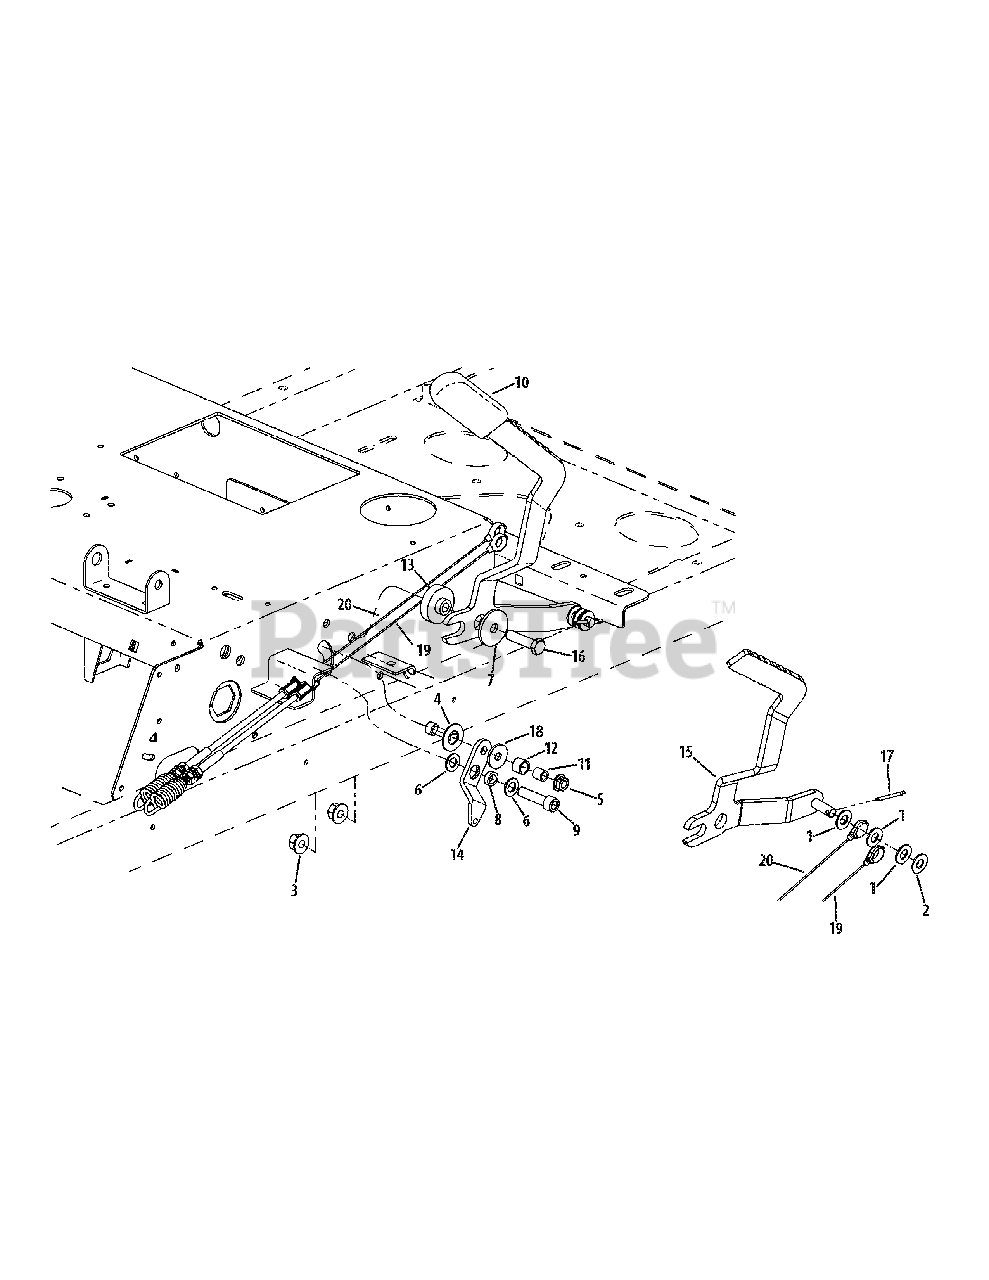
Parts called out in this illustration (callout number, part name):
1	Flat Washer, .406 x .812 x .062
2	Flat Washer, 3/8
3	Hex Nut, 3/8-16 Flange Lock
4	Slide Washer
5	Flange Lock Nut, 5/16-18
6	Washer, .375 x .738 x .063
7	Flat Washer, .390 x 1/5 x .134
8	Spacer, .380 x .563 x .196
9	Sockethead Capscrew, 3/8-16 x 1.50
10	Parking Brake Grip
11	Spacer, .322 x .438 x .44
12	Spacer, .442 x .563 x .405
13	Step Hub, .379 x 1.5 x .257/.400
14	Lockout Lever Plate
15	Brake Handle
16	Hex Head Cap Screw, 3/8-16 x 1.50
17	Cotter Pin, 1/8 x .75
18	Washer, .345 x 1.00 x .100
19	Left Hand Brake Cable
20	Right Hand Brake Cable
